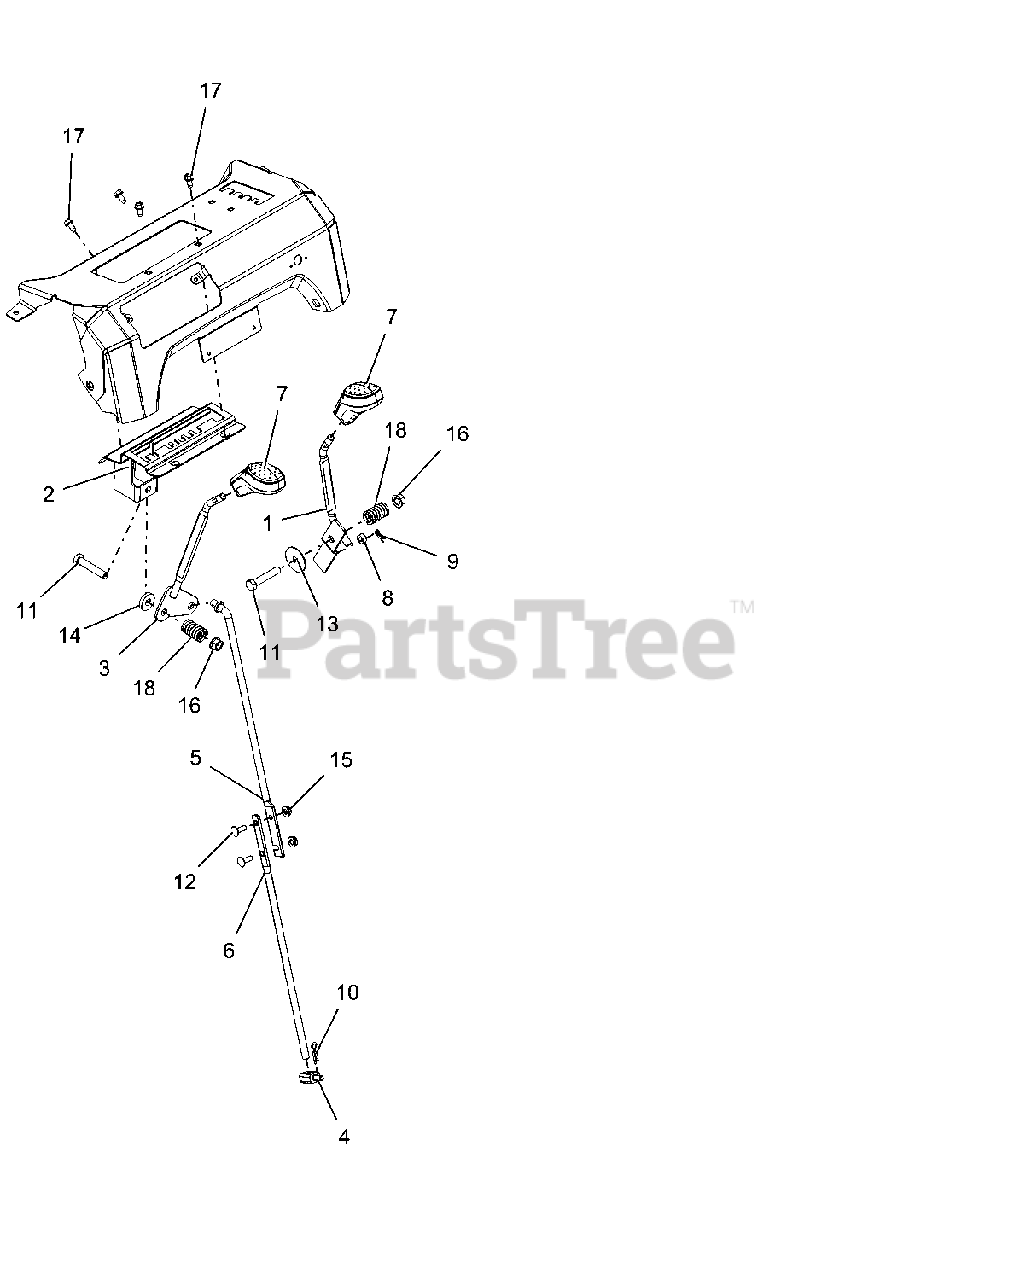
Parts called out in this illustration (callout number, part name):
1	WELDMENT,SM DASH DEFL CONTROL
2	WELDMENT, DETENT PLATE-COMPACT
3	LEVER, CONTROL-SHIFT(WELDMENT)
4	PIVOT,SHIFT ROD .375-16(TRUNN)
5	ROD, SHIFT - UPPER
6	ROD, SHIFT - LOWER
7	KNOB, CONTROL, DASH
8	BSHG-SLV .265X.500X.219
9	PIN-HAIR INT .06X.18X.77
10	PIN-HAIR INT .08X.18X1.18 YWZC
11	@BLT-HEX .38-16X2.00 GR5 YWZC
12	@BLT-RDHDSQNK .25-20X.75 G5YZ
13	WSHR-FL-STL .380X1.50X.062 YWZ
14	WSHR-FL-STL .406X1.00X.188 YWZ
15	@NUT-LK-CTR-FLG .25-20 YWZC
16	@NUT-LK-TOP-FLG .38-16 YWZC
17	SCR-TAP .25-20X.50 HWH TR YWZ
18	SG-COMP .125X.781X1.250
